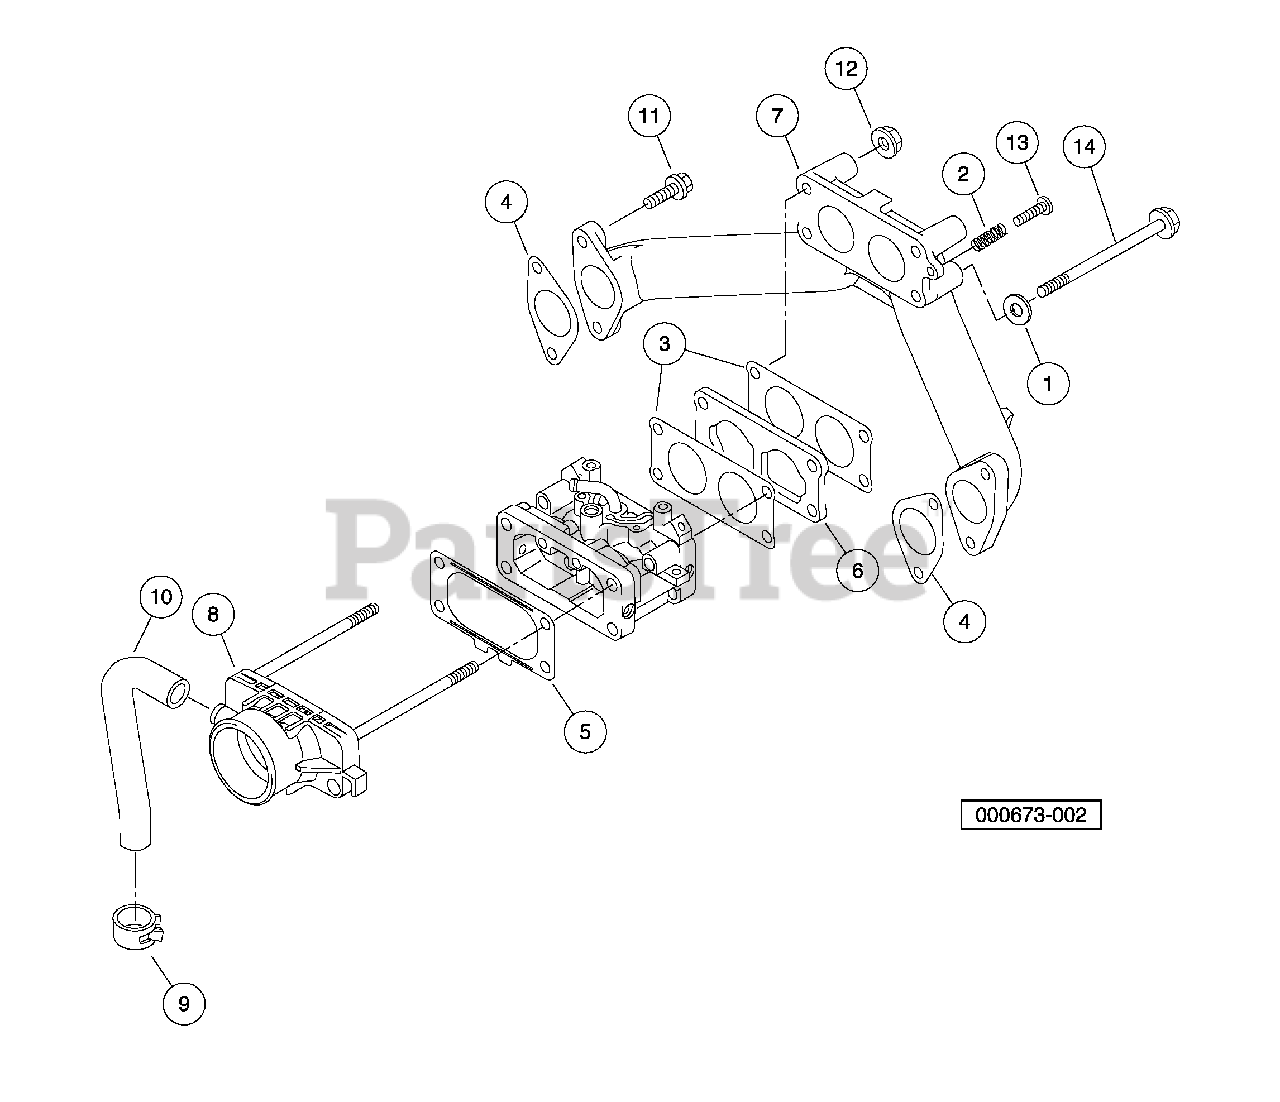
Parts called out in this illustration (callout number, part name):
1	Washer, M6 Flat
2	Spring, Fh
3	Gasket, Carburetor, Fh
4	Gasket, Manifold, Fh
5	Gasket, Air Filter, Fh
6	Insulator, Manifold, Fh
7	Manifold, Intake, Fh
8	Pipe, Intake Adapter, Fh
9	Clamp, Crankcase Vent, Fh
10	Tube, Crankcase Vent, Fh
11	Bolt, Flanged, M6 X 20, Kaw
12	Nut, Carburetor, M6
13	Screw, Carburetor, M4 X 20
14	Bolt, Flg, Carburetor, M6x105
